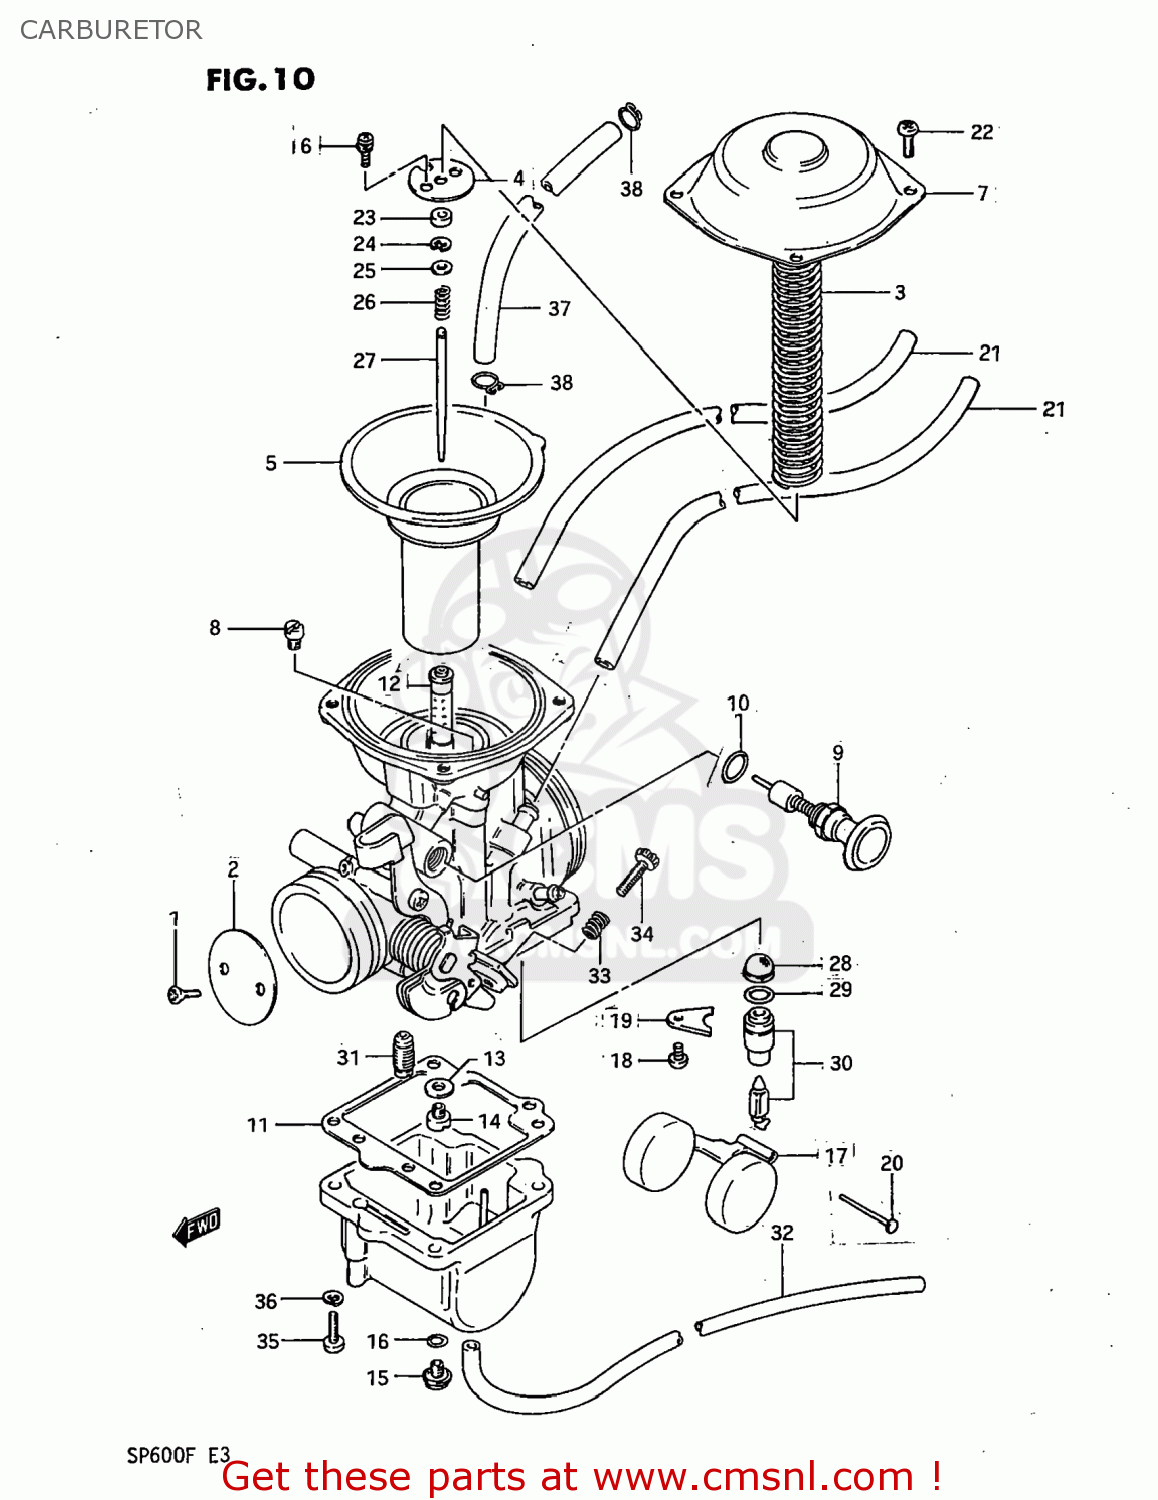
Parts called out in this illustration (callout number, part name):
1	SCREW
2	VALVE,THROTTLE (BUTTERFLY)
3	SPRING,DIAPHRAGM
4	PLATE
5	DIAPHRAGM ASSEMBLY
6	SCREW
7	COVER
8	JET,MAIN
9	VALVE,STARTER
10	O RING
11	GASKET,FLOAT CHAMBER (NAS)
12	JET,NEEDLE
13	WASHER
14	JET,MAIN(142.5)
15	PLUG,DRAIN
16	GASKET (NAS)
17	FLOAT
18	SCREW
19	PLATE
20	PIN,FLOAT
21	HOSE
22	SCREW 5X10
23	RING
24	CLIP,NEEDLE
25	WASHER
26	SPRING
27	NEEDLE JET
28	FILTER
29	O RING
30	VALVE ASSEMBLY,NEEDLE
31	JET,PILOT(47.5)
32	HOSE
33	SPRING
34	SCREW,THROTTLE STOP
35	SCREW
36	LOCK WASHER
37	HOSE CARBURETOR
38	CLIP
